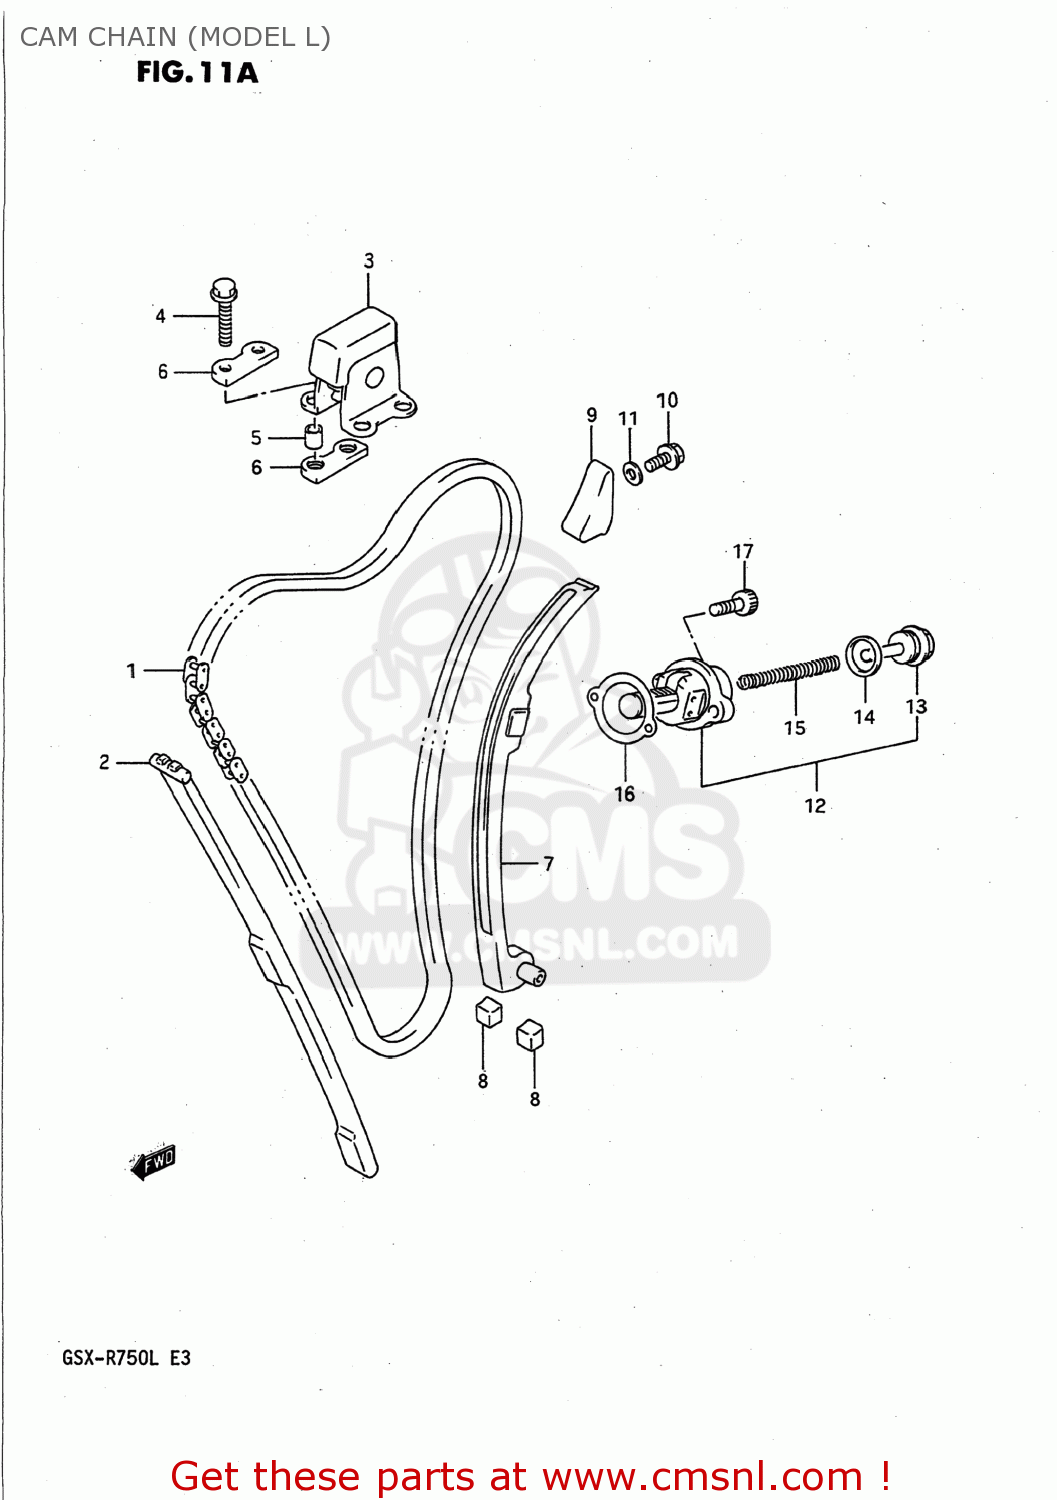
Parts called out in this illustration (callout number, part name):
1	CHAIN,CAMSHAFT DRIVE
2	GUIDE,CAM CHAIN NO.1
3	IDLER,CAM CHAIN
4	BOLT 6X25
5	SPACER
6	CUSION,IDLER
7	TENSIONER,CAM CHAIN
8	CUSHION,CAM CHAIN TENSIONER
9	GUIDE,CAM CHAIN NO.2
10	BOLT
11	GASKET(5.8X13X1.2) (NAS)
12	ADJUSTER ASSEMBLY,TENSIONER
13	PLUG
14	GASKET (NAS)
15	SPRING
16	GASKET,TENSIONER ADJUSTER (NAS)
17	BOLT
